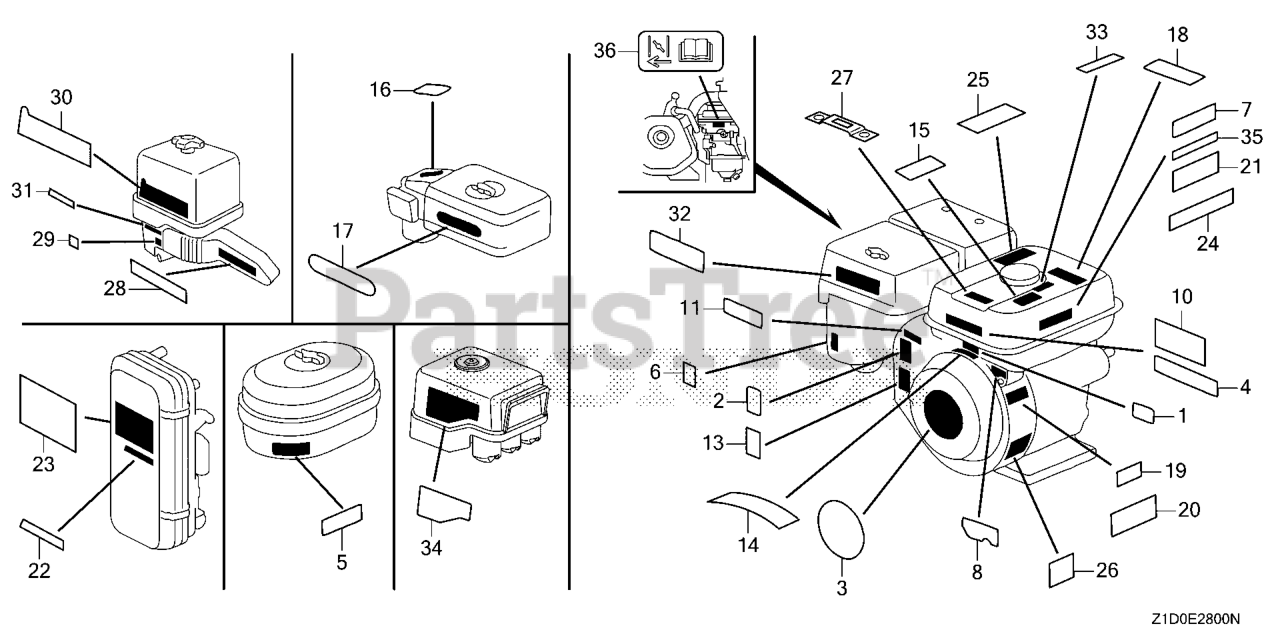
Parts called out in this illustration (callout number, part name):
3	EMBLEM (GX270)
6	MARK, CHOKE
11	MARK, THROTTLE INDICATION
